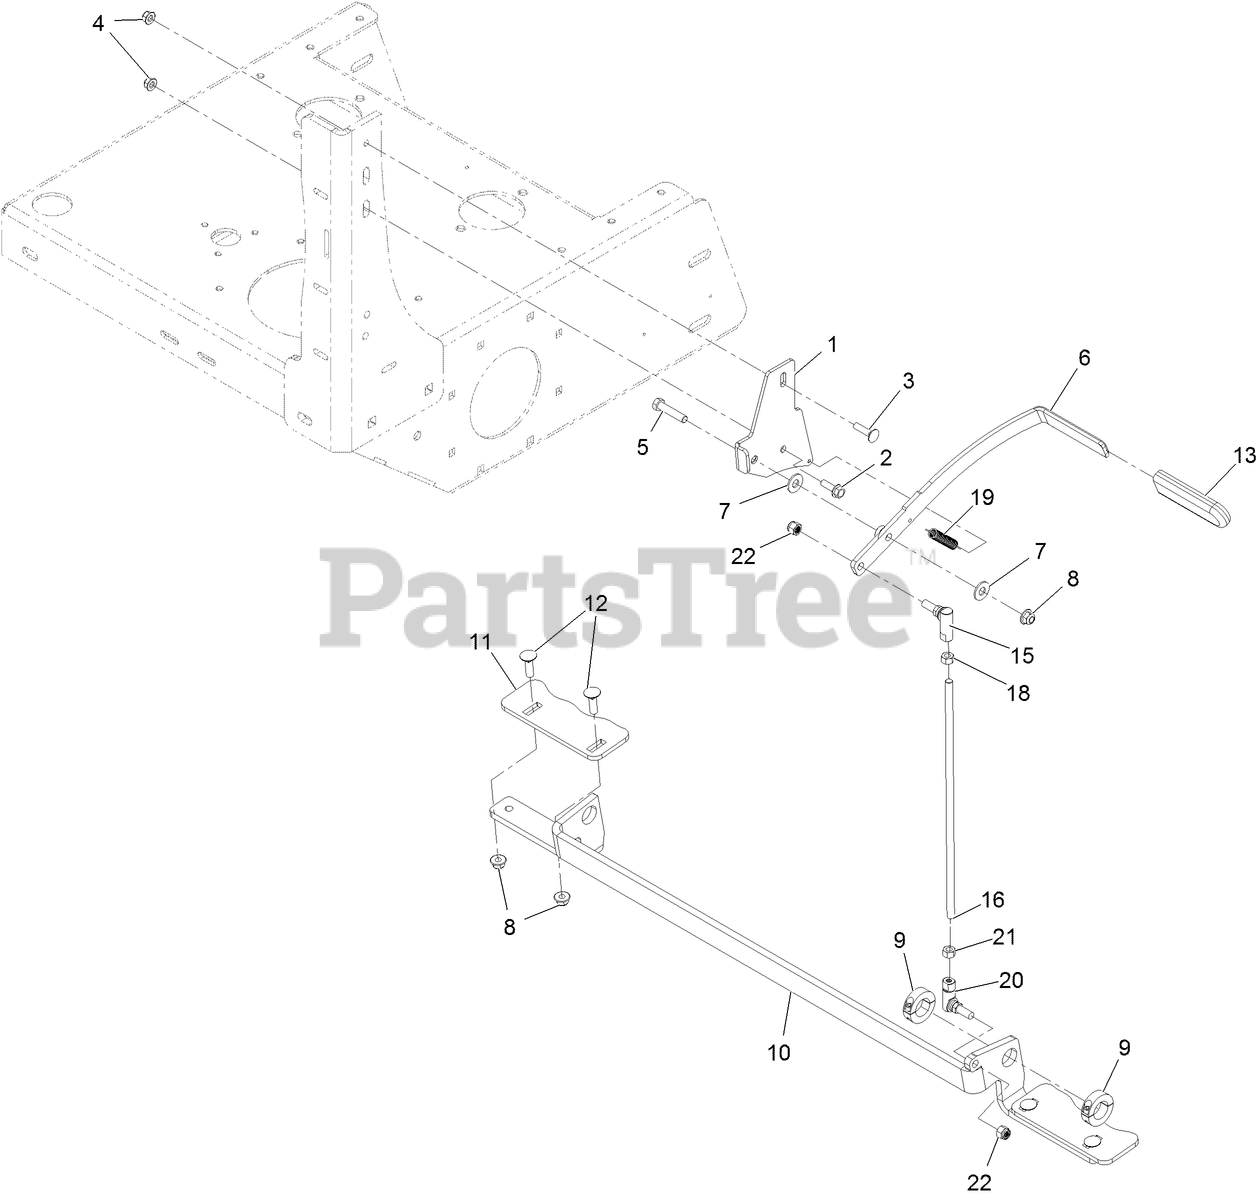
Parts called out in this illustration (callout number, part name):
1	PLATE-BRAKE
2	SCREW-HH
3	Bolt-Carriage 5/16-18 X 1 1/4
4	NUT-HF, NI
5	SCREW-HH
6	HANDLE-BRAKE
7	WASHER-PLAIN
8	NUT-HF, NI
9	COLLAR-LOCKING
10	PIVOT-BRAKE, ROD
11	PAD-BRAKE
12	Bolt-Carriage 3/8-16 X 1 1/4
13	GRIP-LEVER
15	BALL JOINT-SS
16	BRAKE ROD 14.5"
18	NUT-HEX
19	SPRING-EXTENSION
20	BALL JOINT-SS
21	NUT-HEX, LH
22	XREF 126-4803
